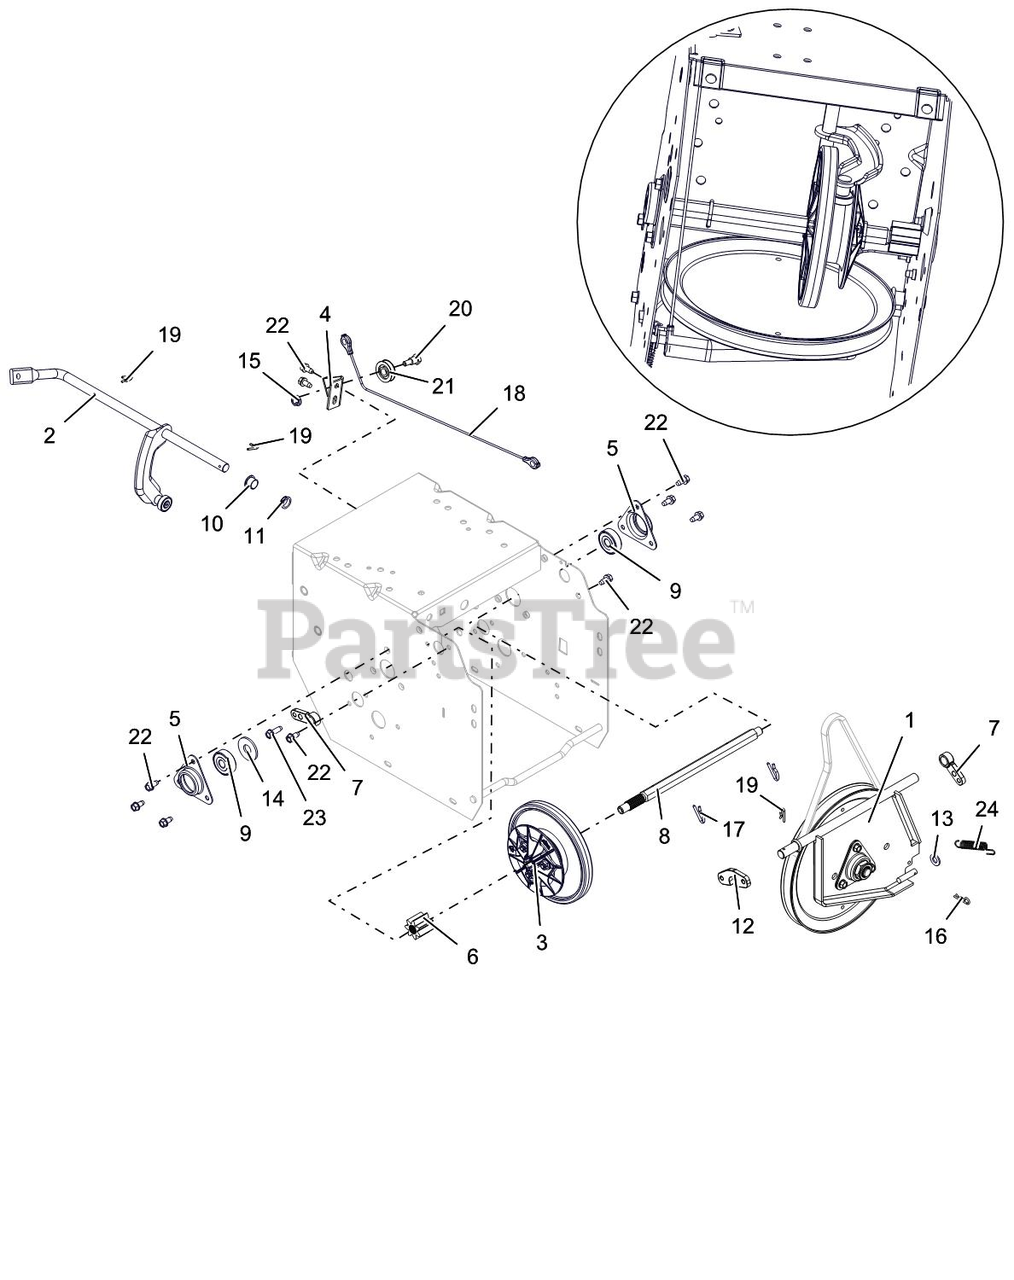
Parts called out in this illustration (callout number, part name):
1	PLATE, SWING - ASSEMBLY
2	ARM, SHIFT-SMALL DASH (WLDMT)
3	DISC, FRICTION DRIVE-ASSEMBLY
4	BRACKET, CABLE PULLEY
5	FLANGE, BEARING
6	GEAR, PINION, 7 TOOTH W/SPLINE
7	SUPPORT BUSHING, SWING GATE
8	SHAFT, HEX W/SPLINE
9	BRG-BALL .437X1.375X.437
10	BUSHING, POLYLINER-.50 SPLIT
11	BUSHING, POLYLINER-.50 SNAPIN
12	SPACER, SWING GATE
13	@WSHR-FL-STL.344X.688X.065YWZC
14	@WSHR-FL-STL.563X1.38X.109YWZC
15	@NUT-LK-CTR-FLG .25-20 YWZC
16	PIN-HAIR INT .08X.18X1.18 YWZC
17	PIN, SPRING CLIP
18	CABLE, LOWER TRACTION (CMPCT)
19	CLIP, SPRING
20	BOLT, SHLDR-.375X.375X.25-20
21	PULLEY, CABLE
22	SCR-TAP .25-20X.50 HWH TR YWZ
23	SCR-TAP-PM .25-20X.75 TR YWZ
24	SPRING, EXT. .043X.438X1.64
